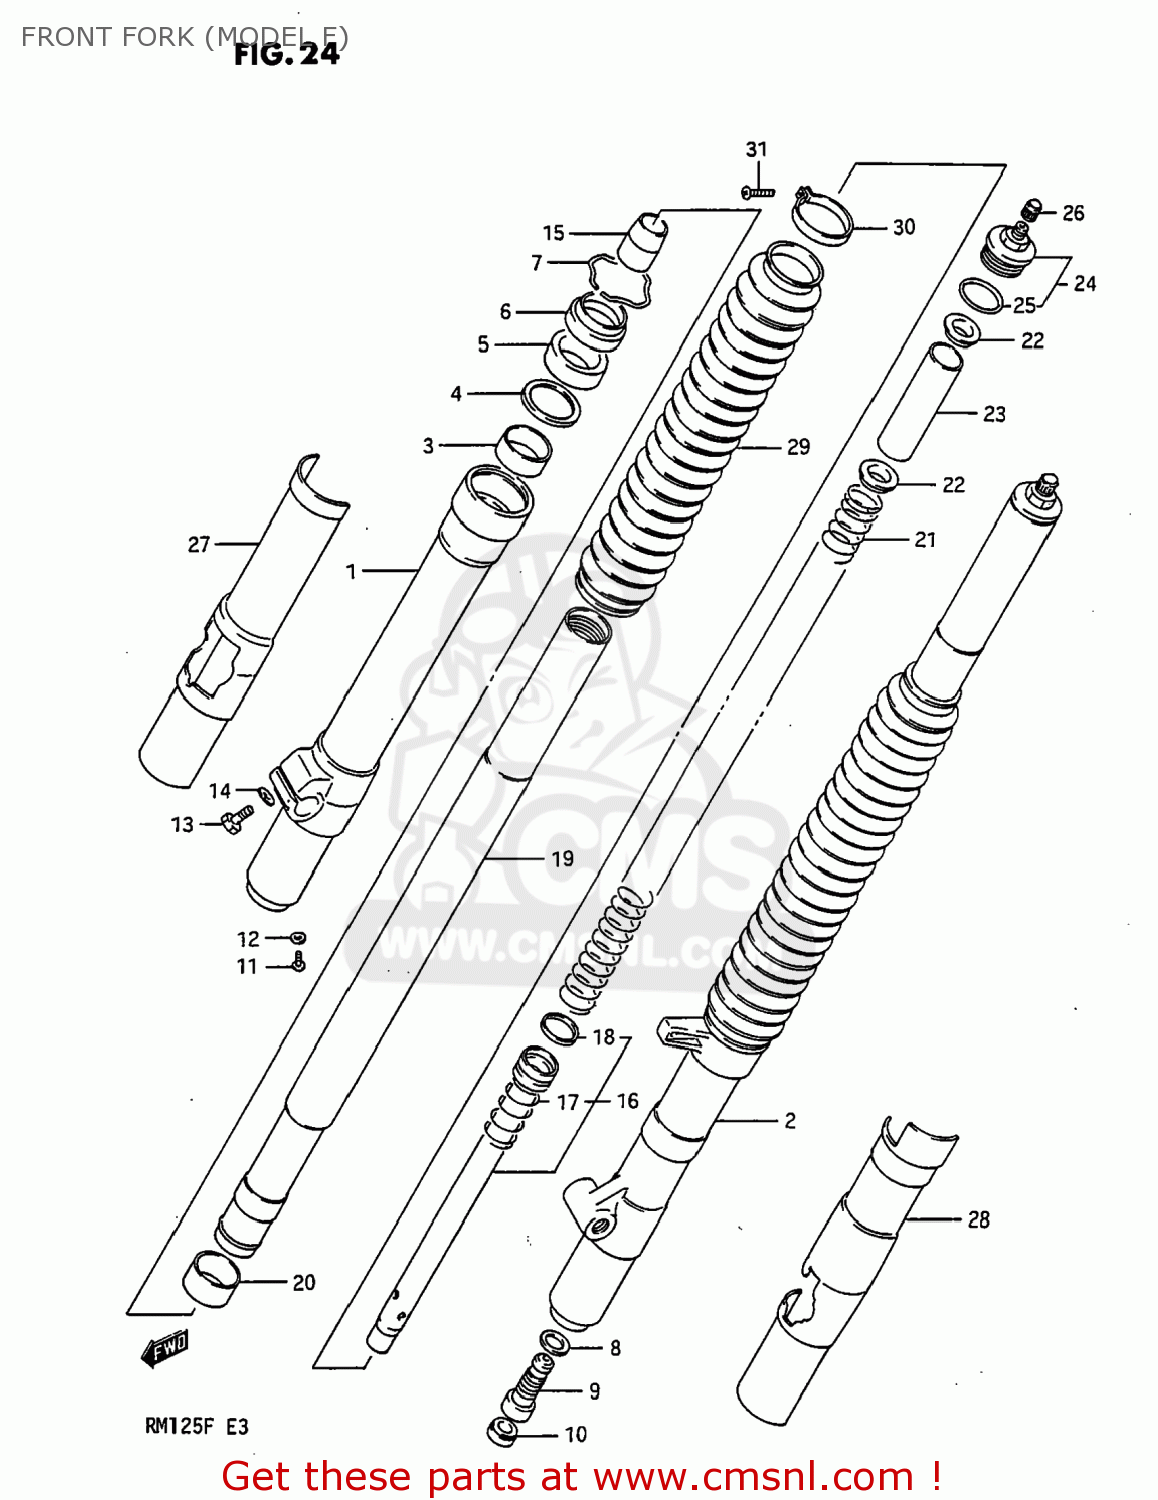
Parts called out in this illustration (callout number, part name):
1	TUBE,OUTER,RIGHT
2	TUBE,OUTER,LEFT
3	METAL,SLIDE
4	WASHER
5	SEAL,OIL
6	SEAL,DUST
7	RING,STOPPER
8	GASKET,FORK CYLINDER
9	VALVE,DF
10	CAP,FRONT FORK DF
11	SCREW 4X6
12	GASKET,DRAIN,PLUG (NAS)
13	BOLT (8X30)
14	WASHER,LOCK,8.
15	PIECE,FRONT FORK OIL LOCK
16	CYLINDER,FRONT FORK
17	SPRING,REBOUND
18	RING,FRONT FORK PISTON
19	TUBE,FORK,INNER
20	PISTON
21	SPRING,FRONT FORK
22	GUIDE,FRONT FORK SPRING
23	SPACER,FRONT FORK SPRING
24	CAP,FORK INNER TUBE
25	O RING
26	CAP
27	PROTECTOR,RIGHT
28	PROTECTOR,LEFT
29	BOOT,FRONT FORK COVER
30	BAND,BOOT,UPPER
31	SCREW 4X10
